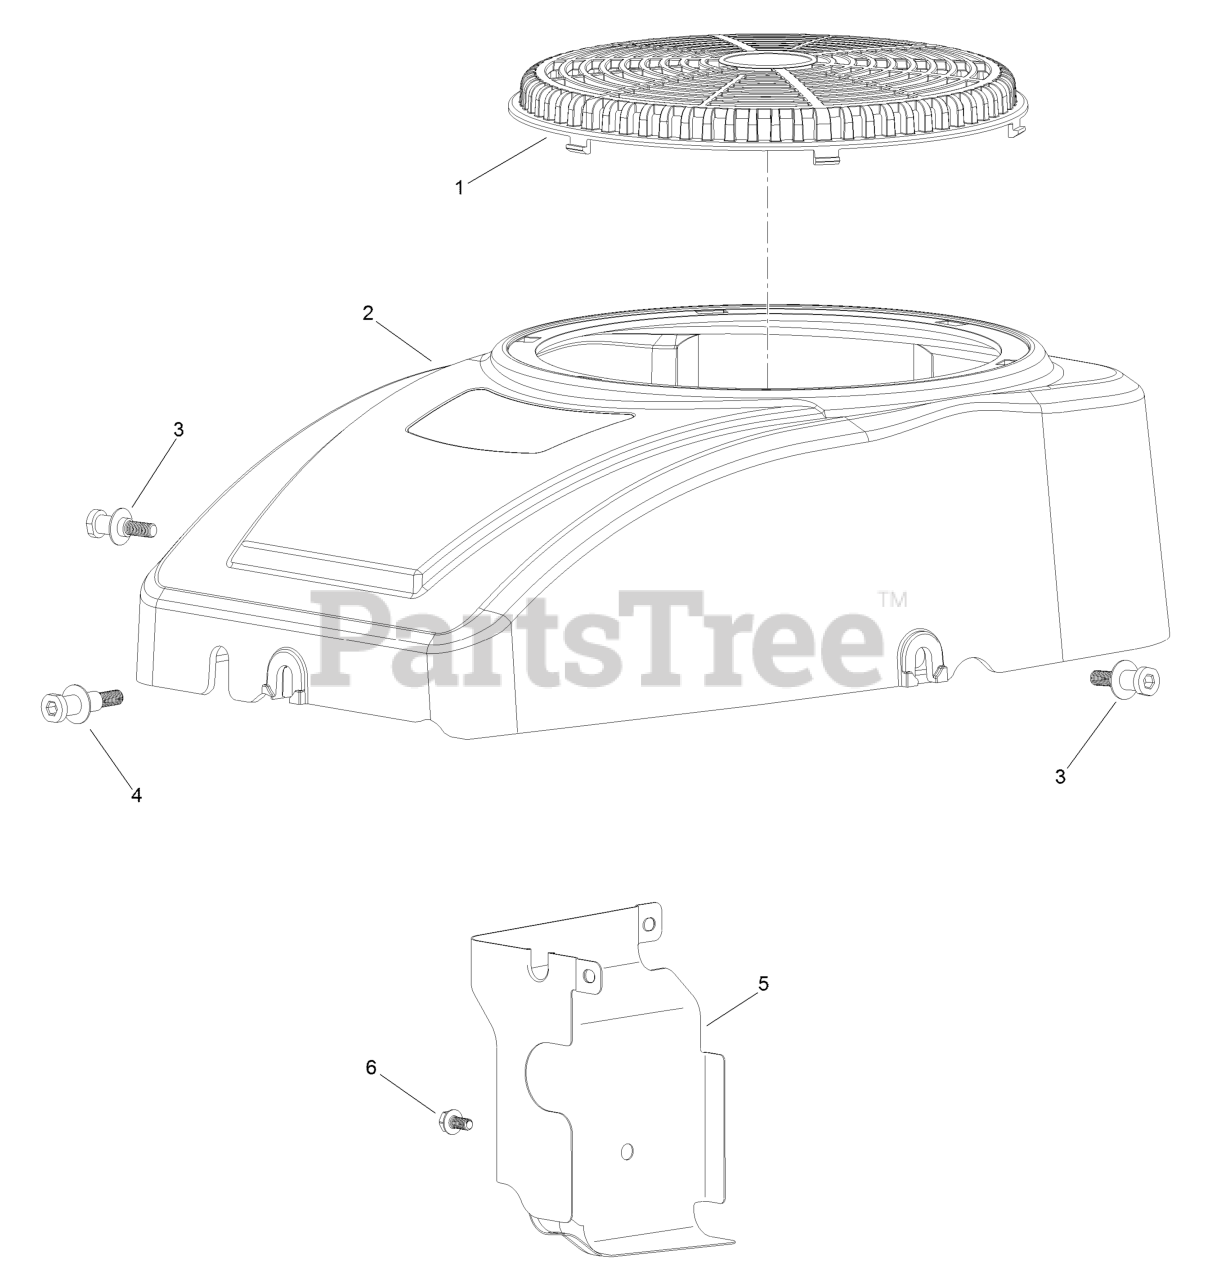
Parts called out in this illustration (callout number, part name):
1	Screen-Stationary
2	Shroud-Fan
3	Screw-Shoulder, HH
4	Screw-Shoulder, HH
6	Screw-HHF
